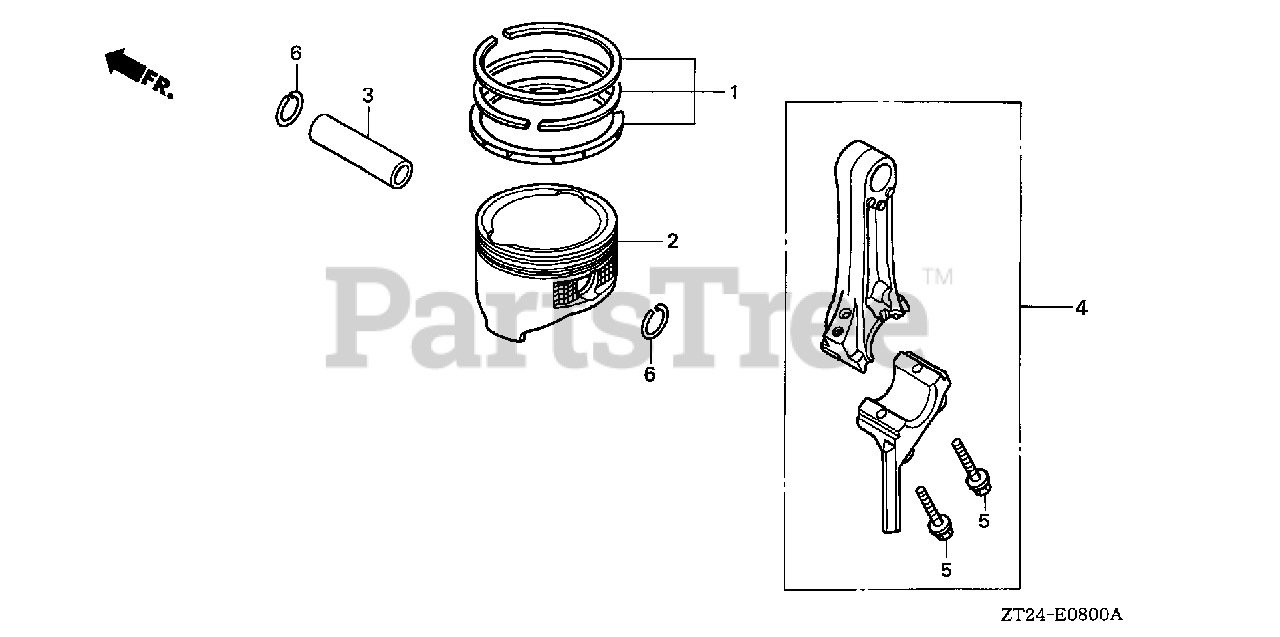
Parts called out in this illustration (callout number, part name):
1	RING SET, PISTON (STD) (TEIKOKU)
2	PISTON
3	PIN, PISTON
4	ROD ASSY., CONNECTING
5	BOLT, CONNECTING ROD
6	CLIP, PISTON PIN (13MM)
